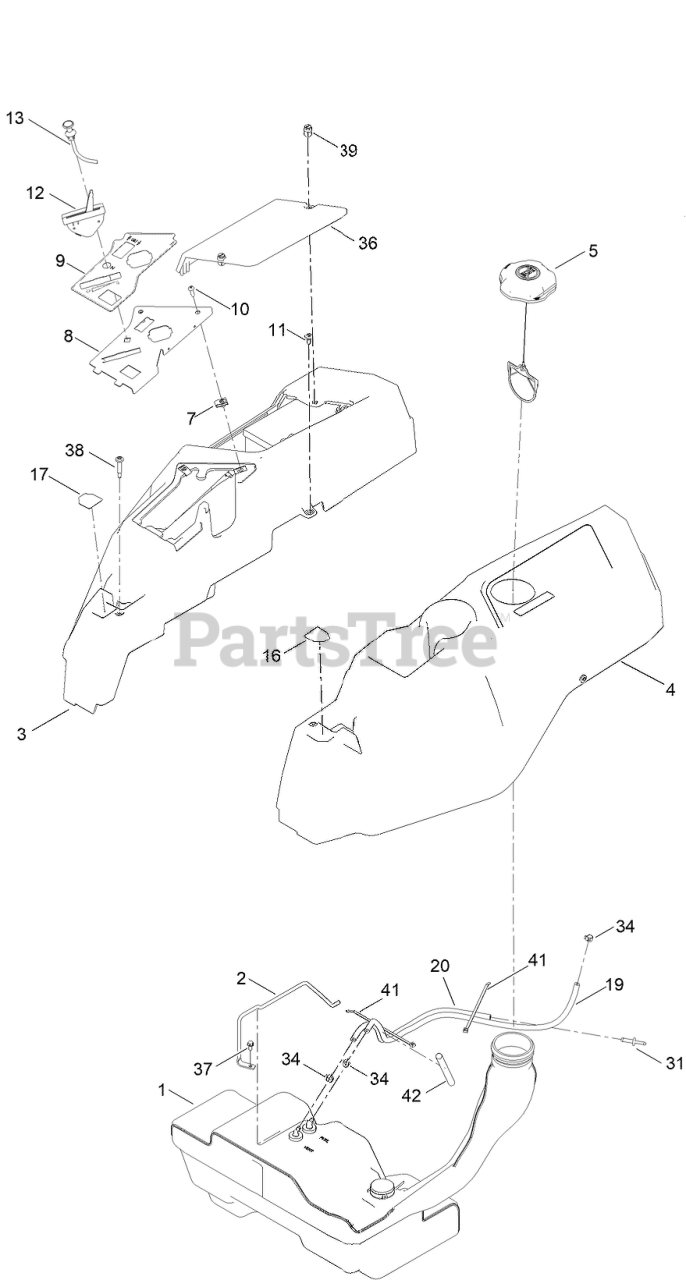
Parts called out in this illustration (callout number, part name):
1	FUEL TANK ASM
2	ROD-HOLD DOWN
3	POD-RH
4	POD-LH
5	CAP-FUEL, RATCHETING
8	PANEL-CONTROL
9	DECAL-PANEL, CONTROL
10	SCREW-PRH
11	SCREW-SHOULDER
12	CABLE-THROTTLE
13	CABLE-CHOKE
16	DECAL-LEVER, CONTROL (LH)
17	DECAL-LEVER, CONTROL (RH)
19	HOSE-FUEL
20	HOSE-FUEL
31	ADAPTOR-ORIFICE
34	CLAMP-HOSE
36	COVER-BATTERY
37	SCREW-HWH
38	SCREW-SHOULDER
39	FASTENER
41	TIE-CABLE
42	SLEEVE-FUEL LINE PROTECTOR
